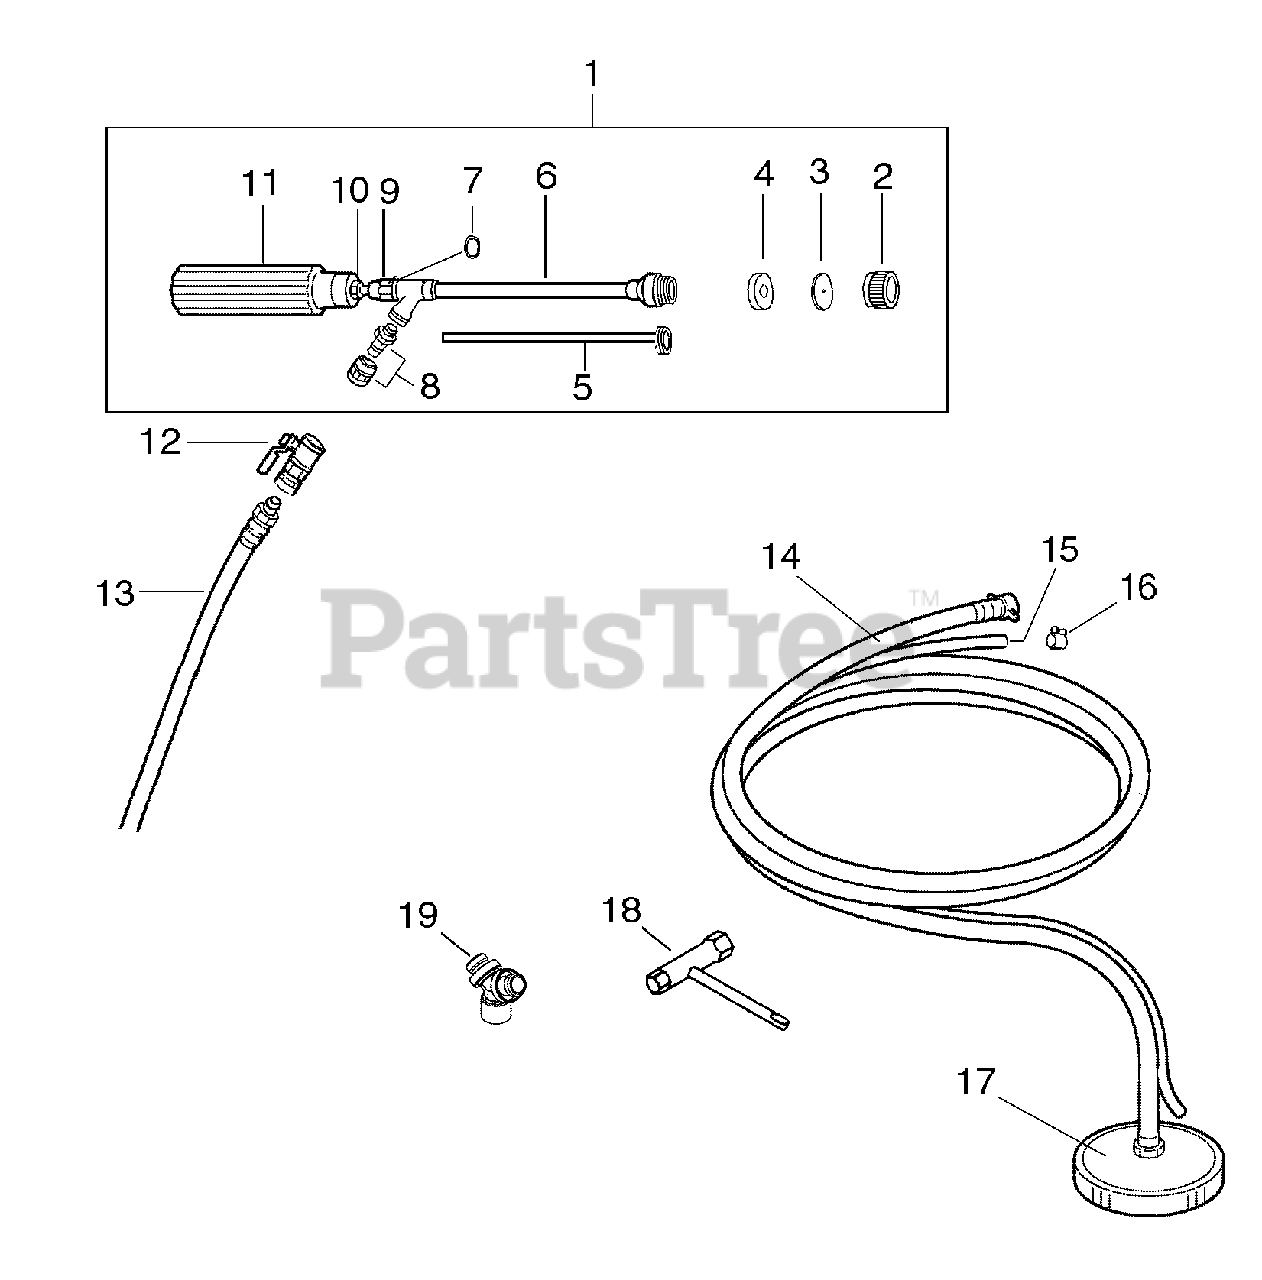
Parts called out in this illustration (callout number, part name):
3	DISK, NOZZLE
4	PIPE, PACKING
5	ADJUSTER, NOZZLE
6	PIPE, NOZZLE
8	COUPLING, HOSE
10	NUT, LOCK
12	PETCOCK
17	STRAINER
18	T-WRENCH 10×19 L= 130
19	ADAPTOR
K042000230	HOSE, 10
